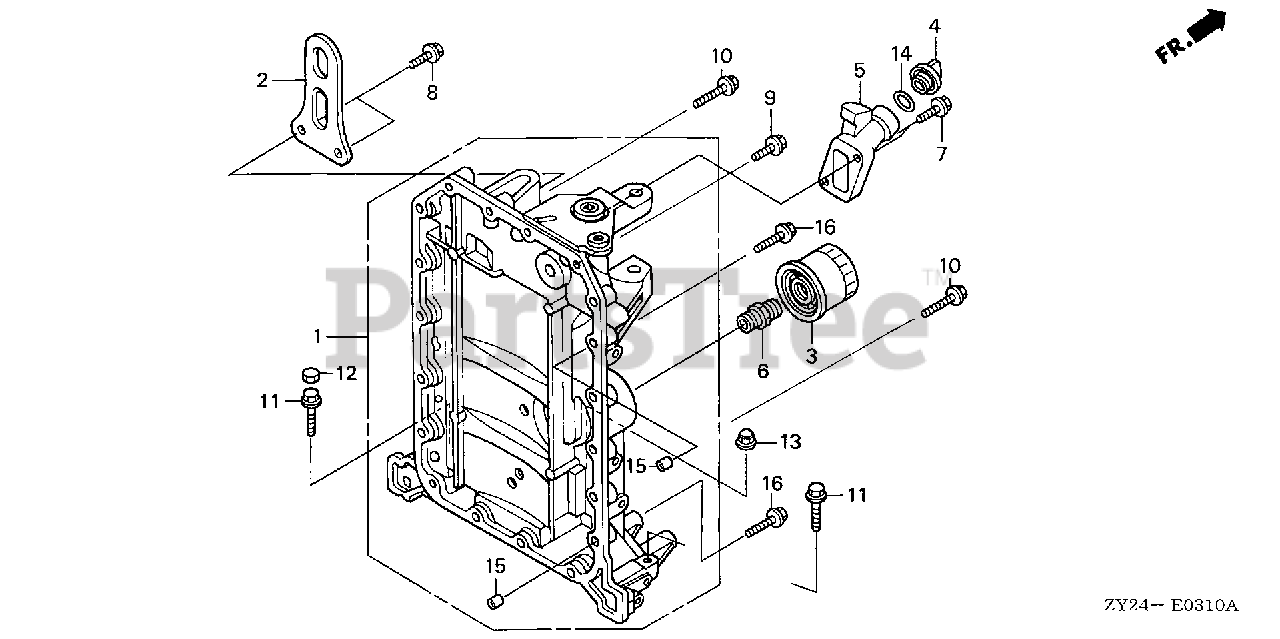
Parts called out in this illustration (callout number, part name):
2	HANGER, ENGINE
3	FILTER, OIL (FILTECH TOYO ROKI) (SOLD INDIVIDUALLY)
3	FILTER, OIL (TOYO ROKI) (SOLD INDIVIDUALLY)
4	CAP, OIL (YELLOW)
5	EXTENSION, OIL FILLER
6	HOLDER, OIL FILTER
7	BOLT, FLANGE (6X22)
8	BOLT, FLANGE (8X20)
9	BOLT, FLANGE (6X32)
10	BOLT, FLANGE (6X55)
11	BOLT, FLANGE (10X55)
12	CAP, BOLT (10MM)
13	NUT, FLANGE CAP (10MM)
14	O-RING (26X2.7)
15	PIN, DOWEL (8X14)
16	BOLT, FLANGE (6X32)
16	BOLT, FLANGE (6X37)
